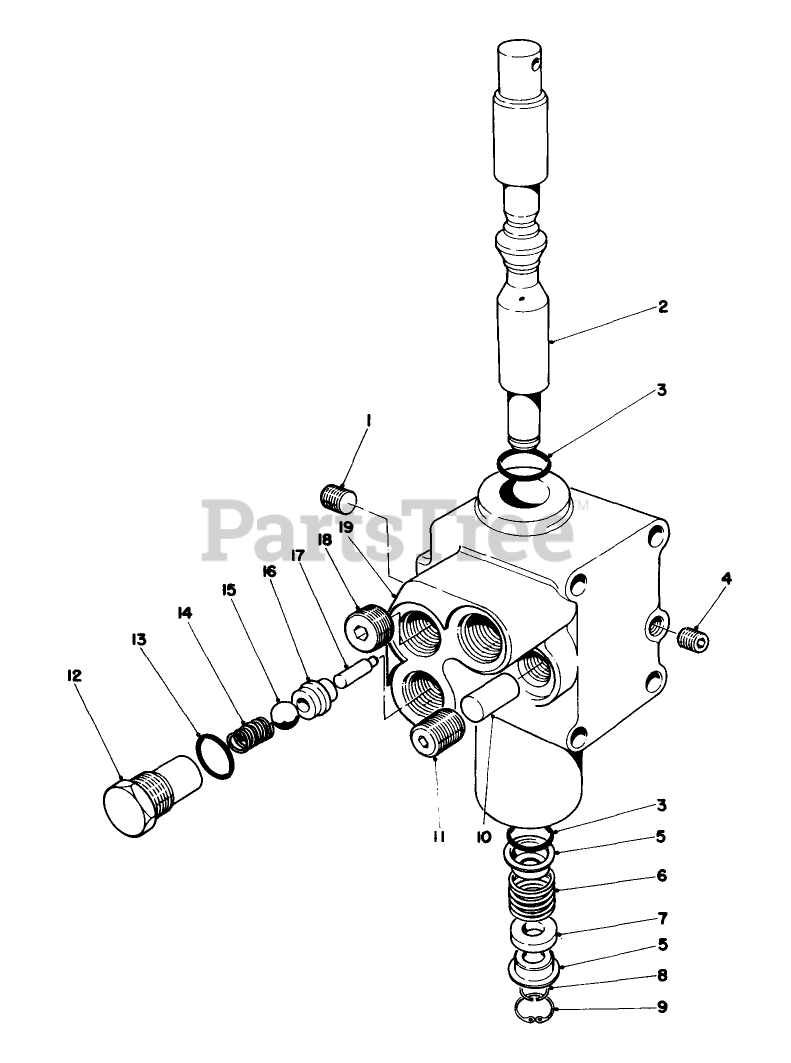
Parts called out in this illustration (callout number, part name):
2	SPOOL
3	O-RING
5	RETAINER
6	SPRING
7	FLOAT SPACER
8	RING-SNAP
9	RING-SNAP
13	O-RING
14	SPRING
16	SEAT-VALVE
19	Body
